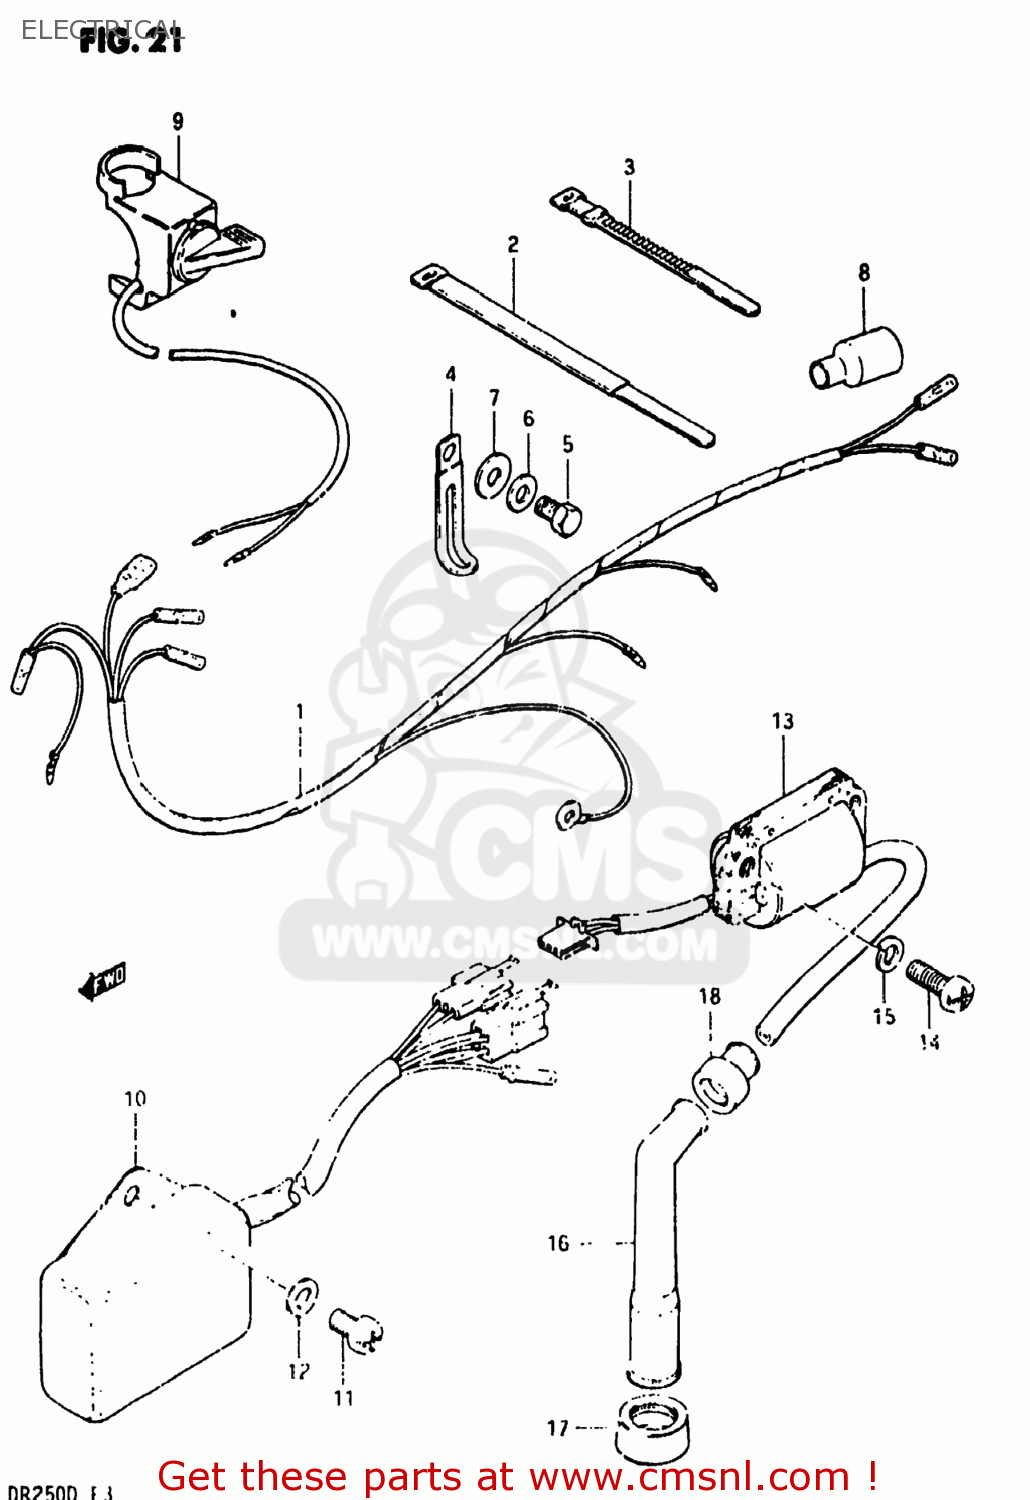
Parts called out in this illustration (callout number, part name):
1	HARNESS,WIRING
2	CLAMP
3	CLAMP(L:120)
4	CLAMP
5	BOLT, UPPER
6	WASHER
7	WASHER
8	BOOT,WIRING HARNESS
9	SWITCH ASSY,ENGINE STOP
10	IGNITER UNIT ASSEMBLY
11	SCREW
12	WASHER
13	COIL ASSY,IGNITION
14	SCREW
15	LOCK WASHER
16	CAP ASSY,SPARK PLUG
17	SEAL,SPARK PLUG
18	SEAL,SPARK PLU
